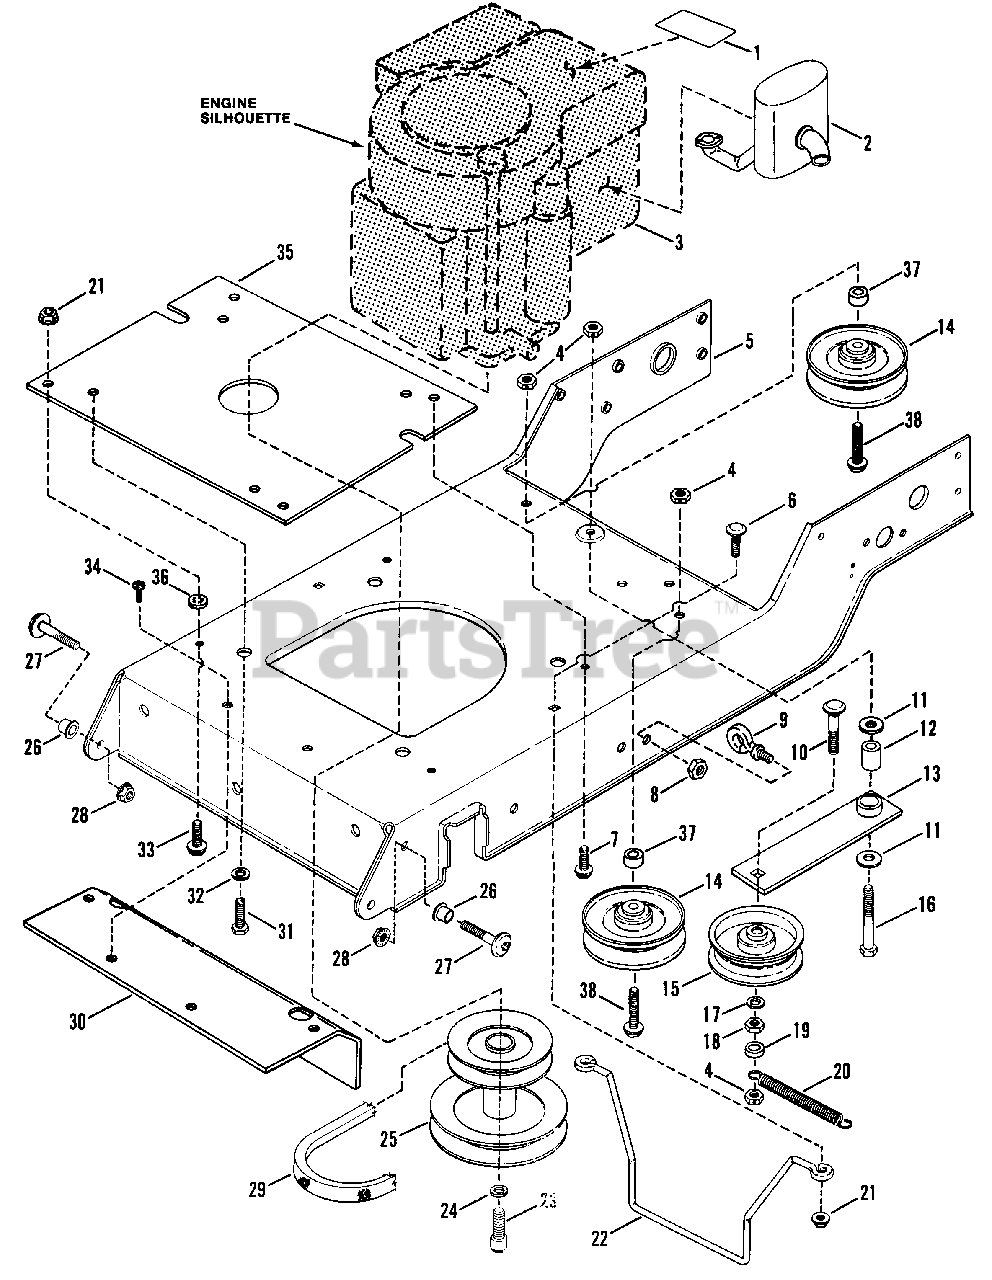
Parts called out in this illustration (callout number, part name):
1	DECAL, Engine 14 HP OHV
2	MUFFLER, Exhaust
4	NUT, 3/8-16 Hex Center Lock
5	BASE, Engine
6	BOLT, 5/16-18 x 3/4" Short Neck Carriage
7	BOLT, 5/16-18 x 3/4" Flange Lock
8	NUT, 5/16-18 Hex Center Lock
9	EYE-BOLT
10	BOLT, 3/8-1B x 2-1/2" Short Neck Carriage
11	WASHER, 7/16 Flat
12	BUSHING, Idler Arm .750 OD x .406 ID x .25 L
13	ARM, Idler
14	PULLEY, Idler, 4" O.D.
15	PULLEY, Idler, 3-3/4" O.D.
16	BOLT, 3/8-16 x 2-1/4" Hex
17	WASHER, 3/8 Split Lock
18	NUT, 3/8-16 Hex
19	SPACER .623 OD x .38 ID x .25 L
20	SPRING, Idler Arm
21	NUT, 5/16-18 Hex Flange Lock
22	GUIDE, Belt
23	CAPSCREW, 7/18-20 x 1" Hex Socket Head
24	LOCKWASHER, 7/16 Split
25	ASSEMBLY, Engine Pulley
26	BUSHING
27	SCREW, Shoulder, 3/8-16 x 1-5/8"
28	LOCKNUT, 3/8-16 Hex Flange
29	V-BELT, Traction Drive, (111.6" EL) LT140H33, LT140H41, & RLT140H33
30	AXLE SUPPORT (No longer available)
31	BOLT, M8-1.25 x 25mm Hex Head
32	WASHER, 5/16 Split Lock
33	BOLT, 5/16-18 x 1" Hex Flange Lock
34	SCREW, 5/16-18 x 7/8" Truss Head (Torx)
35	SPACER, Kohler Engine
36	RETAINER, 5/16 Bolt
37	SPACER .750 OD x .390 ID x .5 L
38	BOLT, 3/8-16 x 1-3/4" Hex Flange Lock
